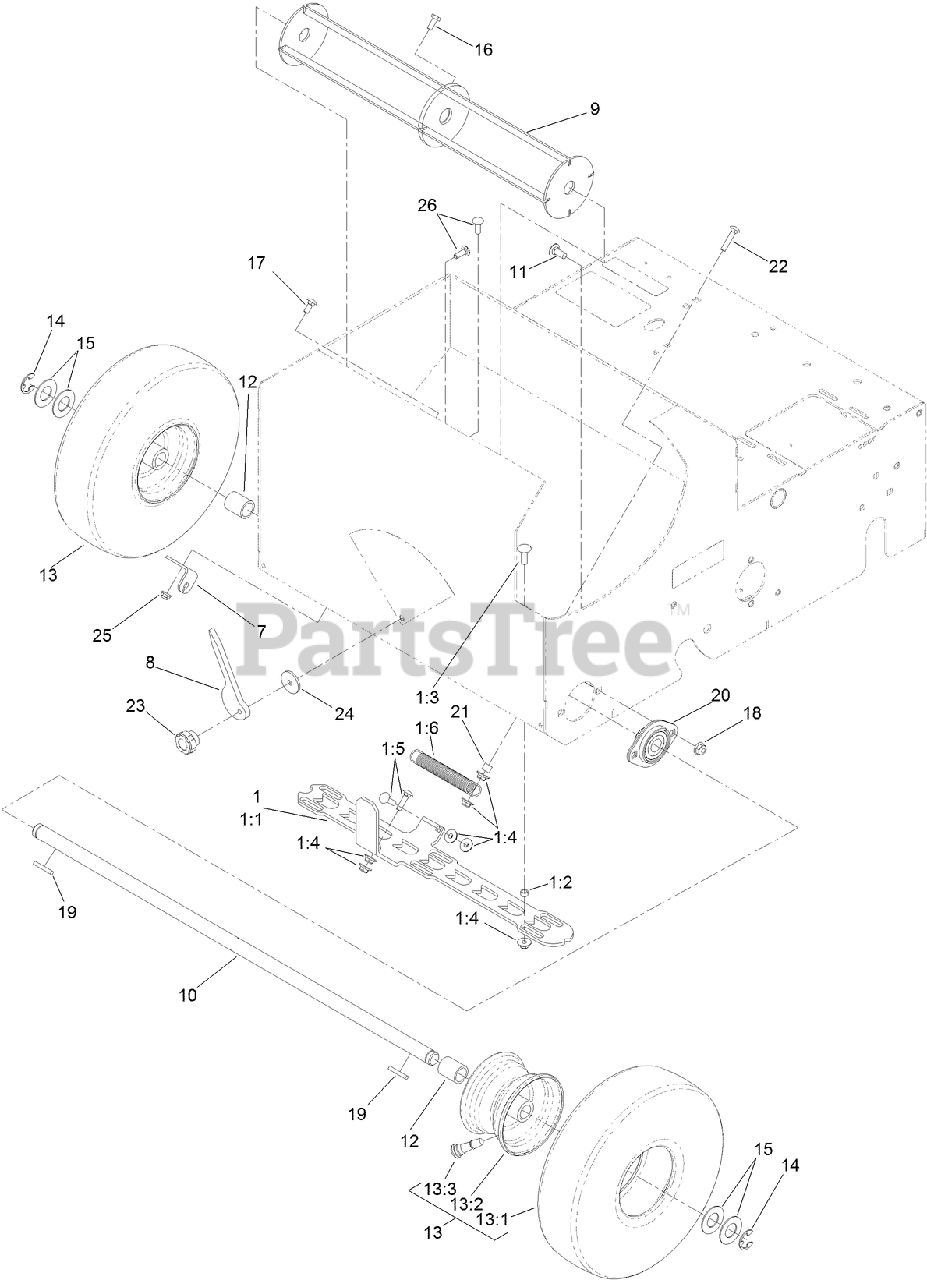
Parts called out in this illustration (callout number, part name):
1	SEED GATE KIT
1:1	GATE-SEED
1:2	SPACER
1:3	BOLT-CARR
1:4	NUT-HF
1:5	SCREW-CARR
1:6	SPRING-EXTENSION
7	BRACKET-SEED FLOW
8	GAUGE-SEED FLOW
10	AXLE-FRONT
11	SCREW-CARR
12	Spacer
13	WHEEL ASM
13:2	WHEEL-RIM
13:3	VALVE
14	E-RING
15	WASHER-FLAT
16	SCREW-HH
17	SCREW-CARR
18	NUT-HF, NI
19	KEY-SQUARE
20	BEARING
21	SPACER
22	SCREW-CARR
23	KNOB-CHUTE
24	WASHER
25	NUT-HF
26	BOLT-CARR
